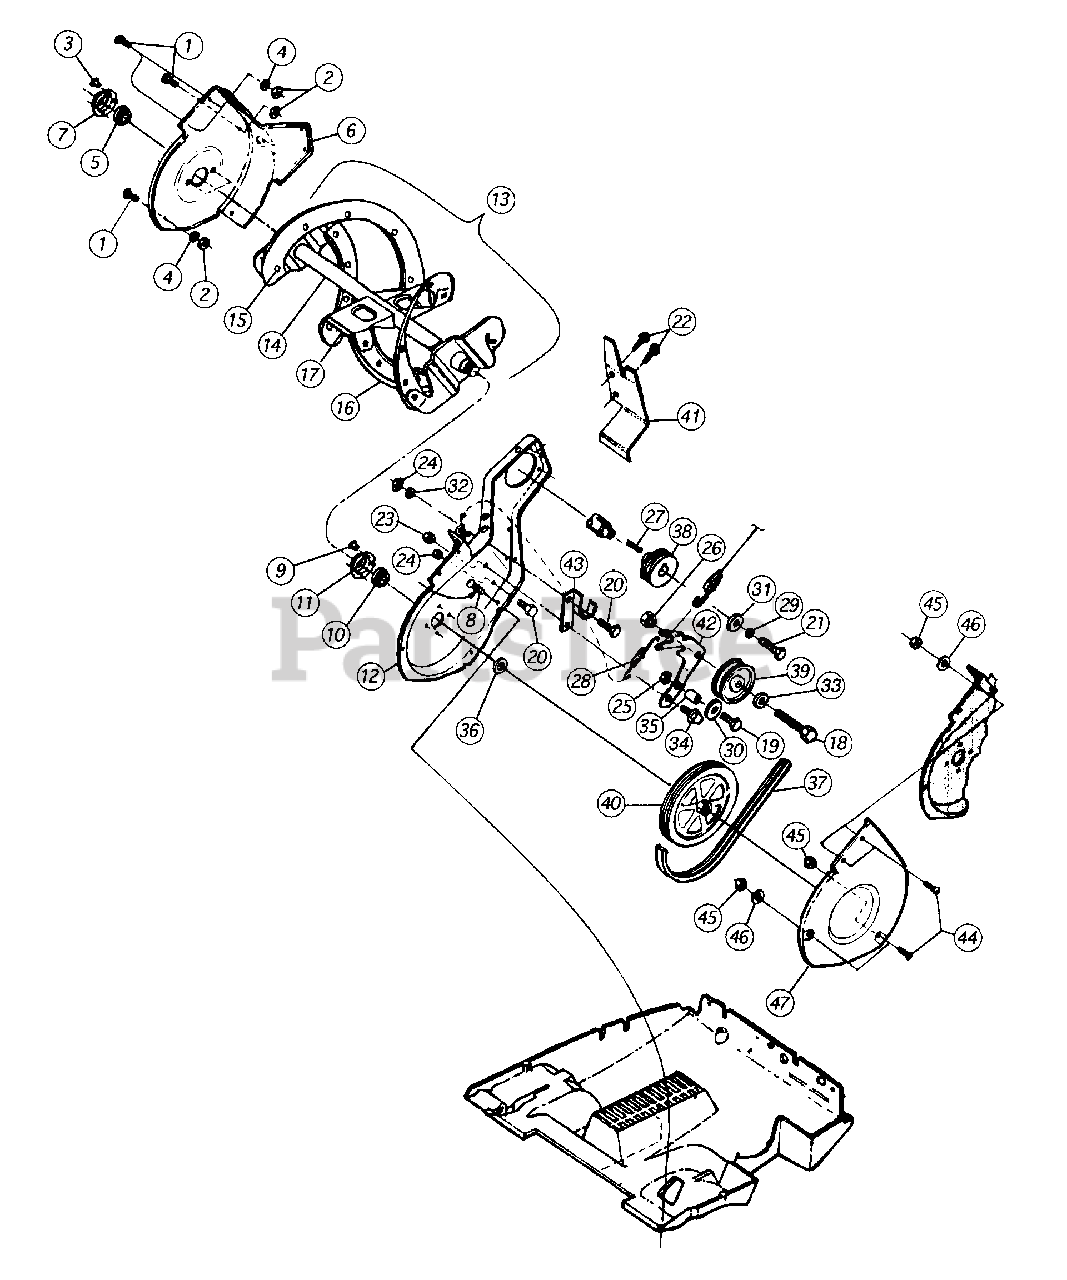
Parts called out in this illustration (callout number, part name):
1	Truss Machine Screw
2	Hex Nut
3	Rivet
4	Flat Washer
5	Ball Bearing, Auger Axle
8	Hex Screw: 1/4 - 20 x .625 Gr 2
9	Rivet .252 Dia x .31
10	Ball Bearing, Auger Axle
11	Retainer Bearing
14	Auger Assembly, Weld.
15	Rivet, Truss
16	Auger Blade
17	Auger Paddle
18	Hex Screw: 3/8 - 16 x 1.50 Gr 5
19	Hex Screw: 1/4 - 20 x 1.0 Gr 5
20	Hex Screw: 1/4 - 20 x .75 Gr 5
21	Hex Screw: 5/16 - 24 x .88 Gr 2
22	Hex Screw
23	Sems Nut: 5/16 - 18
24	Sems Nut: 1/4 - 20
25	Lock Nut: 1/4 - 20
26	Flanged Lock Nut
27	Key
28	Extension Spring
29	Lock Washer
30	Flat Washer: .344 ID x 1.12 OD
31	Flat Washer: .385 ID x .87 OD x .092
32	Flat Washer: .25 ID x .62 OD
33	Flat Washer: .406 ID x .81 OD x .051
34	Shoulder Screw
35	Spacer, Brake Belt
36	Spacer, Auger Pulley
37	Belt, Auger Drive
38	Engine Pulley
39	Idler Pulley
40	Auger Pulley
41	Shield, Bolt
42	Idler Arm
43	Bracket, Belt
44	Machine Screw #10 - 24 x .62
45	Hex Nut
46	Flat Washer: .218 ID x .62 OD x .063
